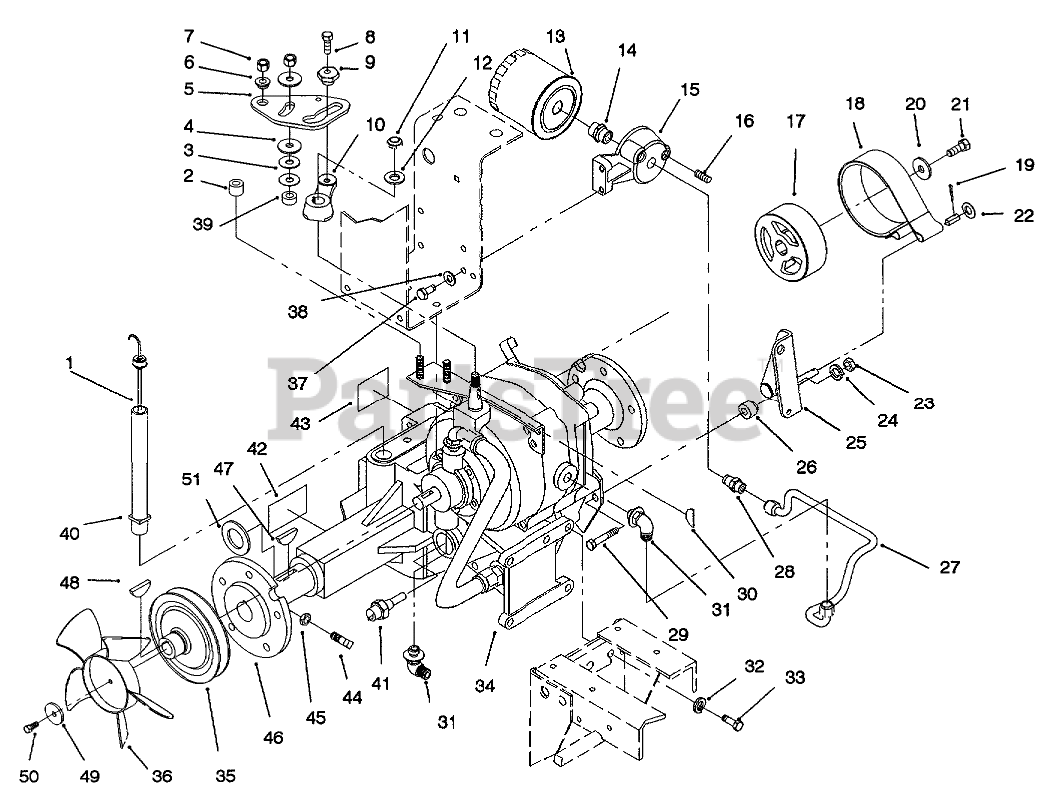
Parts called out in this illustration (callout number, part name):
1	ASSY DIPSTICK (BLACK)
2	Spacer-Pivot
3	WASHER-SPRING DISC
4	FRICTION WASHER
5	CAM-SPEED CONTROL (NS)
6	CAM-SPACER
8	Screw-HH
10	ARM-SPEED CONTROLB
11	NUT-LOCK, NI
12	WASHER-FLAT
13	OIL FILTER ASM
14	FITTING
15	BASE-FILTER
17	DRUM-BRAKE
18	ASSY-BRAKE BAND
19	PIN-COTTER
20	WASHER
21	SCREW-HH, LOCK
22	WASHER-FLAT
23	NUT-LOCK, NI
24	WASHER-FLAT
25	Pivot Arm-Brake
26	BUSHING-BRAKE PIVOT
27	ASS'Y-TUBE FILTER
28	FITTING
29	SCREW-HH
30	KEY-WOODRUFF
31	ELBOW
32	WASHER-LOCK
33	SCREW-HH
33	HYDRO TRANSAXLE ASM
34	Transaxle/Intl Decal
35	PULLEY
36	NYLON FAN-L-CW
37	SCREW-HH
38	WASHER-LOCK
39	SPACER-FRICTION
40	NIPPLE-TRANS FILL
41	SENSOR-HYDRO OIL HOT
42	Decal-Danger
43	DECAL-UNIDRIVE
44	SCREW-SET, SQH
45	NUT-JAM
46	HUB-WHEEL
47	KEY-WOODRUFF
48	KEY-WOODRUFF
49	WASHER
50	SCREW-HEX HD CAP
51	WASHER-THRUST
